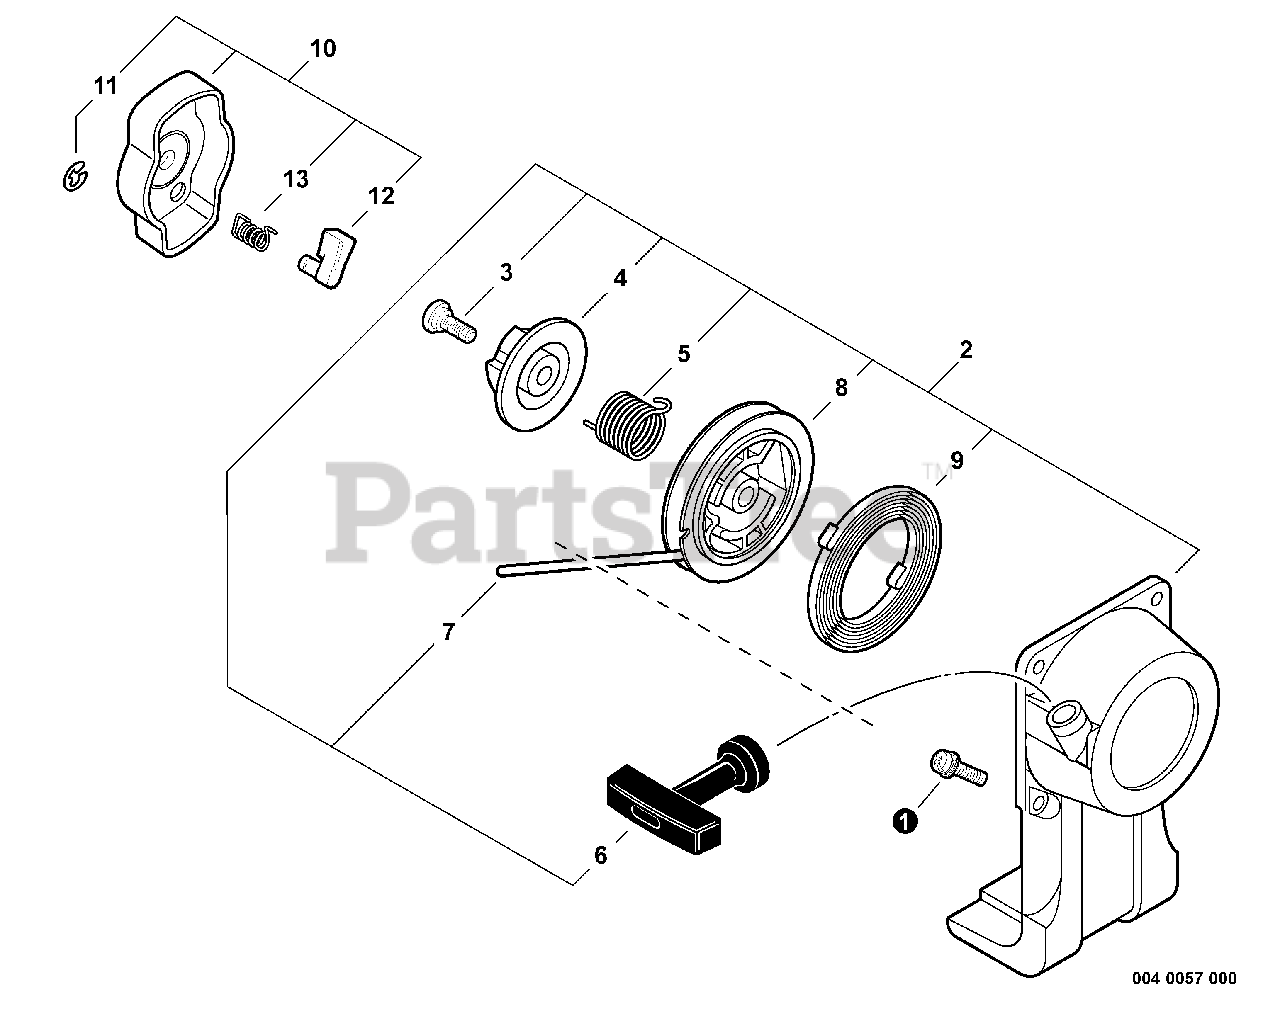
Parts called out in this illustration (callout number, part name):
1	SCREW - 4X16
2	STARTER ASSY
3	SCREW
4	PLATE, CAM
5	SPRING, DAMPER
6	GRIP, STARTER
7	ROPE, STARTER
8	REEL, ROPE
9	SPRING, REWIND
10	STARTER PAWL ASSY
11	RING, RETAINING - 4
12	PAWL, STARTER
13	SPRING, RETURN
